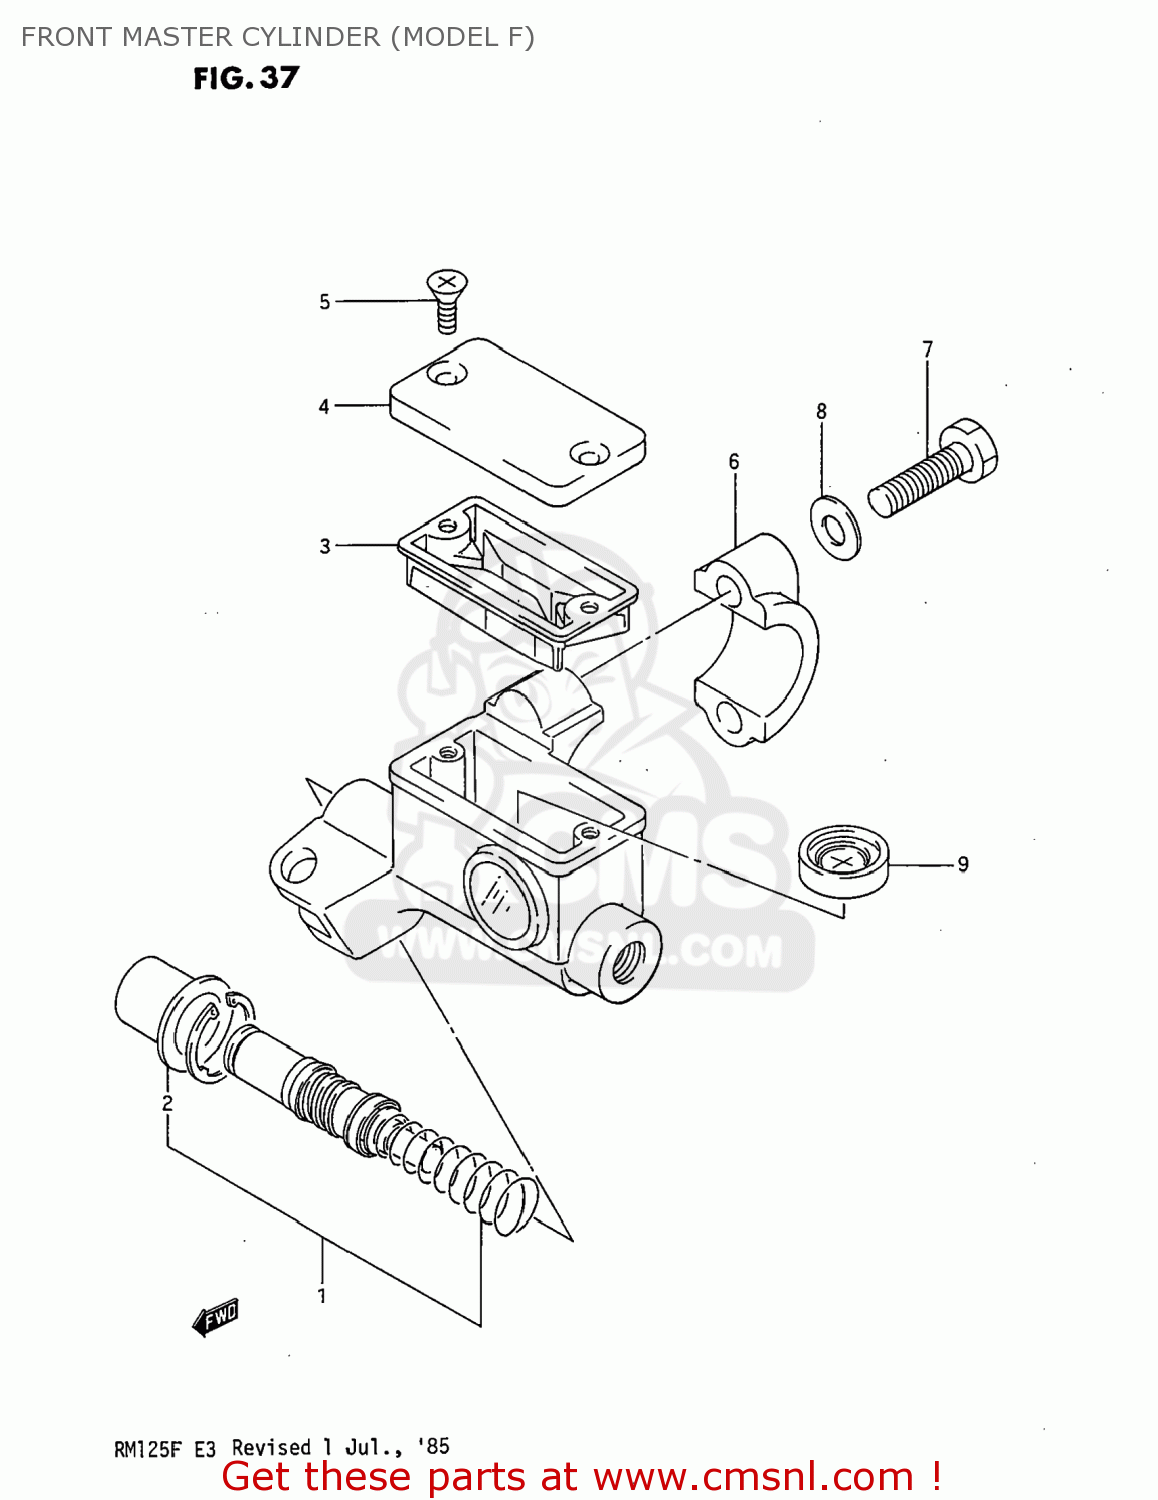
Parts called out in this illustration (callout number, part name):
1	PISTON/CUP SET,FR MASTER
2	BOOT
3	DIAPHRAGM
4	CAP
5	SCREW
6	HOLDER,MASTER CYLINDER
7	BOLT
8	WASHER
9	SEPARATOR
